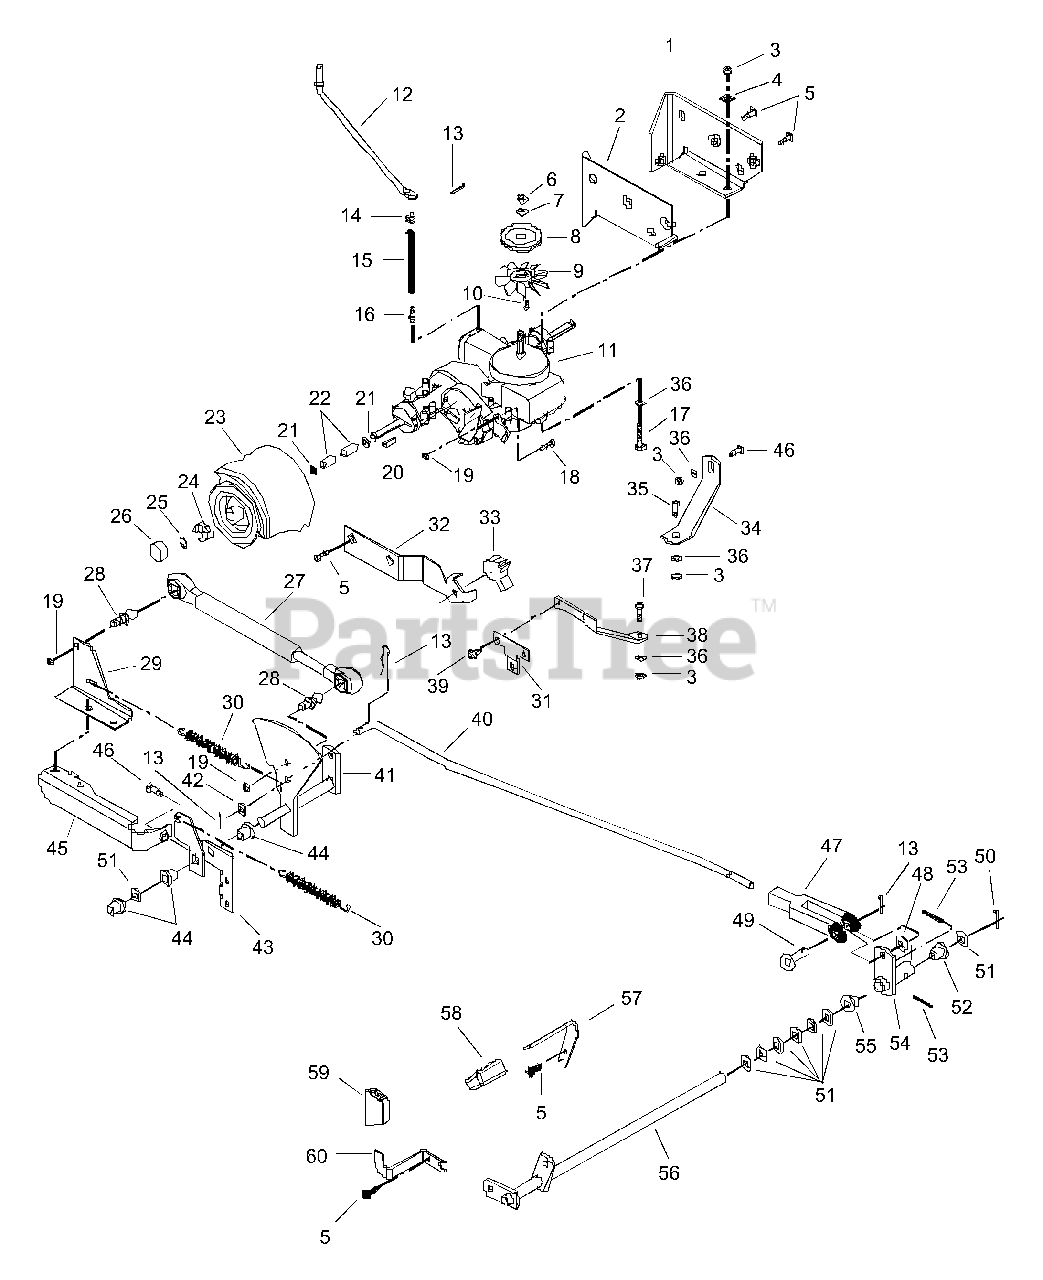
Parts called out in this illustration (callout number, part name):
1	Mount-Transmission Left Hand
2	Mount-Transmission Right Hand
3	Nut-Locking-Center .312-18
4	Washer-Flat-Steel .328 x .875 x .062
5	Screw-Tapping .375-16 x .75
6	Nut-Jam .50-20 Grade 2
7	Washer-Lock .50 x .125 Reg.
8	Sheave-Transaxle
9	Fan-Black Nylon
10	Screw-Tapping 10-24 x .484
11	Transaxle-Hyd
12	Rod-Transmission Disconnect
13	Pin-Cotter .09 x .75
14	Cap-Vent 1/2" Hydro-Gear
15	Hose-Vent .50 ID x 7.50 Long
16	Fitting-Straight 1/2" O-Ring Hydro-Gear
17	Bolt-Hex .31-18 x 2.50 Grade 5
18	Bolt-Hex .31-18 x .75 Grade 5
19	Nut-Locking-Center .312-18
20	Key-Square .188 x 2.0 x .188
21	Washer-Flat-Steel .755 x 1.375 x .062
22	Bushing-Sleeve .750 x 1.125 x 1.062
23	Tire/Wheel Assembly 20 x 8.00-8 2 Ply
23	Rim
23	Tire 20 x 8.00-8
24	Spindle Cup
25	Ring-Retaining-External .750 x .050
26	Hub Cap
27	Damper-Hydraulic
28	Stud-Ball
29	Anchor-Spring-Top
30	Spring-Tension .085 x .60 x 5.13
31	Support - Shift Arm
32	Mount-Magnet
33	Magnet-HS
34	Strap-Torque Left Hand
35	Bolt-Hex .31-18 x 1.50 Grade 5
36	Washer-Flat-Steel .344 x .688 x .065
37	Bolt-Hex .31-18 x 2.25 Grade 5
38	Strap-Torque Right Hand
39	Screw-Tapping .312-18 x .50
40	Rod-Shift
41	Arm-Shift
42	Washer-Flat-Steel .406 x .812 x .065
43	Pivot-Reverse
44	Bushing-Flange .508 x .645 x .459 x .75
45	Anchor-Spring-Bottom
46	Bolt-Hex .31-18 x .75 Grade 5
47	Yoke .31-24 x 2.250
48	Washer-Flat-Steel .390 x .750 x .125
49	Pin-Clevis .312 x .822
50	Pin-Cotter .12 x 1.0
51	Washer-Flat-Steel .520 x .827 x .062
52	Bushing-Flange .515 x .750 x .745 x 1.00
53	Pin-Groove .188 x 1.25
54	Arm & Hub
55	Bushing-Flange .502 x 1 x .750
56	Shaft-Pedal
57	Pedal-Forward
58	Cover-Pedal-Forward
59	Cover-Pedal-Reverse
60	Pedal-Reverse
